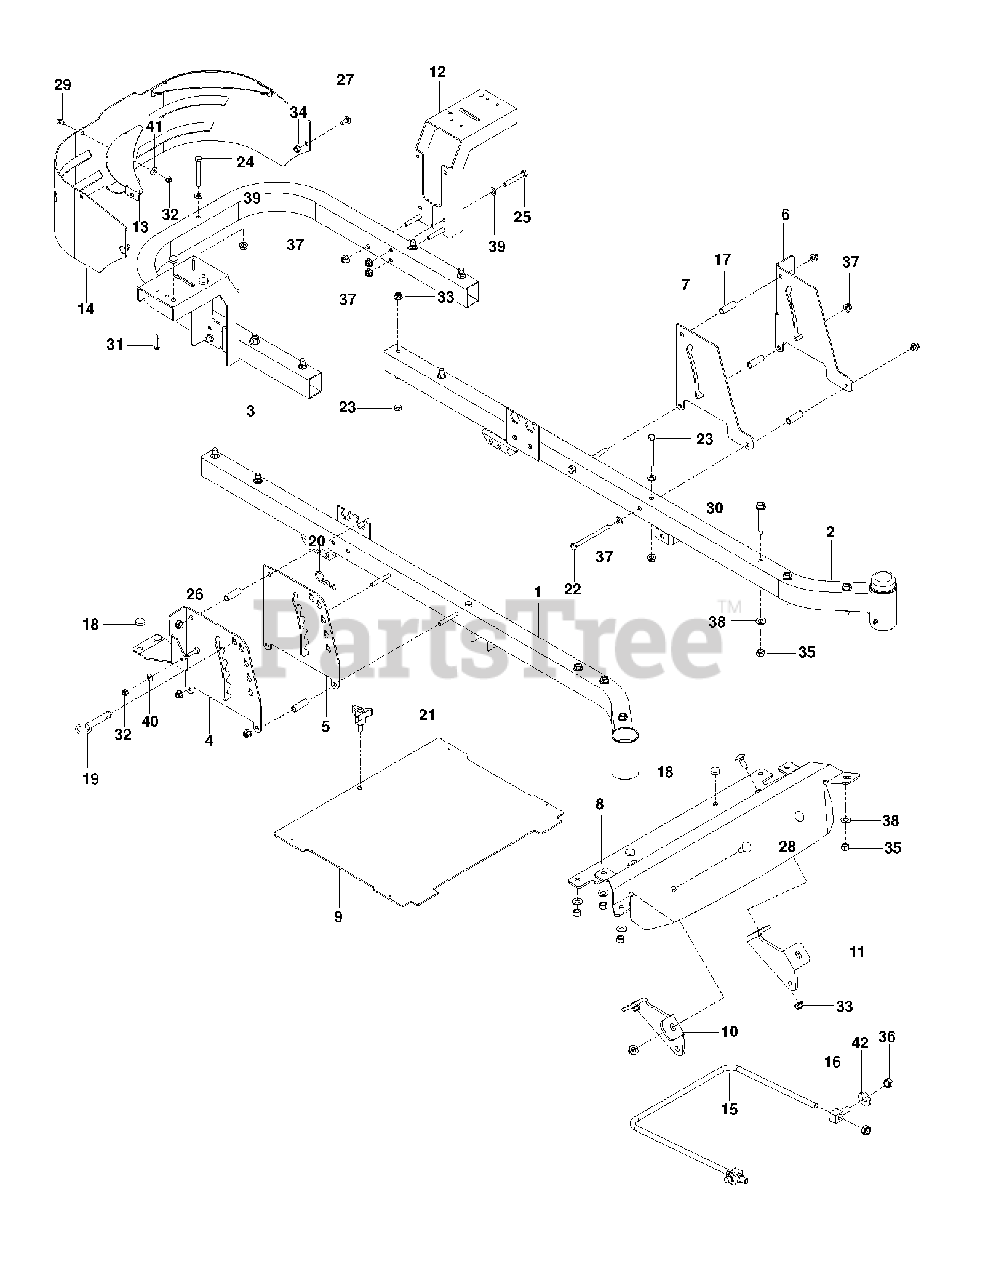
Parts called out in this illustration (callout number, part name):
1	FRAME, RT, ORANGE
2	FRAME, LT, ORANGE
3	FRAME TUBE, REAR, ORANGE
4	PLATE, DECK HEIGHT, BLK EZ
5	PLATE, DECK HEIGHT, BLACK
6	PLATE, OUTER BRAKE, BLACK
7	PLATE, BRAKE LATCH, BLACK
8	FOOT REST WIDE ORG
9	PLATE, FOOT W/DECALS EZ
10	MOUNT, STRUT, RT, BLK
11	MOUNT, STRUT, LT, BLK
12	SUPPORT, FENDER, BLACK
13	SUPPORT, CORNER, ORANGE
14	GUARD, REAR, ORANGE
15	LINK, FRONT SUSP.
17	SPACER, .334 ID X .5 OD X 1.5
18	GROMMET, BUMPER
20	HAIRPIN #4
21	KNOB W/STUD
22	HCS 5/16C X 4
23	HCS 3/8C X 3
24	HCS 5/16C X 2-3/4
26	HCS 1/4C X 1
27	BOLT 5/16C X 3/4" CARRIAGE
28	RHSNB 3/8C X 1
29	RHSSNB, 1/4-20X5/8
30	ENGINE BOLT, SPECIAL
31	SCR #10-12X1-1/2HEX WASH HD ZD
32	RP_NUT 1/4-20 NYLOC
33	NUT 3/8-16 HEX FLG NYLOC ZD
34	NUT 5/16 NYLOC
35	NUT HEX 3/8-16 NYLON, THIN
36	7/16-14 HEX NUT W/NYL RING ZD
37	5/16-18 NYLOC FLANGE NUT
38	RP WASHER 3/8 FLAT
39	FLAT WASHER 5/16 SAE
40	WASHER 1/4 SAE
41	WASHER 1/4 FLAT
42	WASH USS FLAT 1/2
